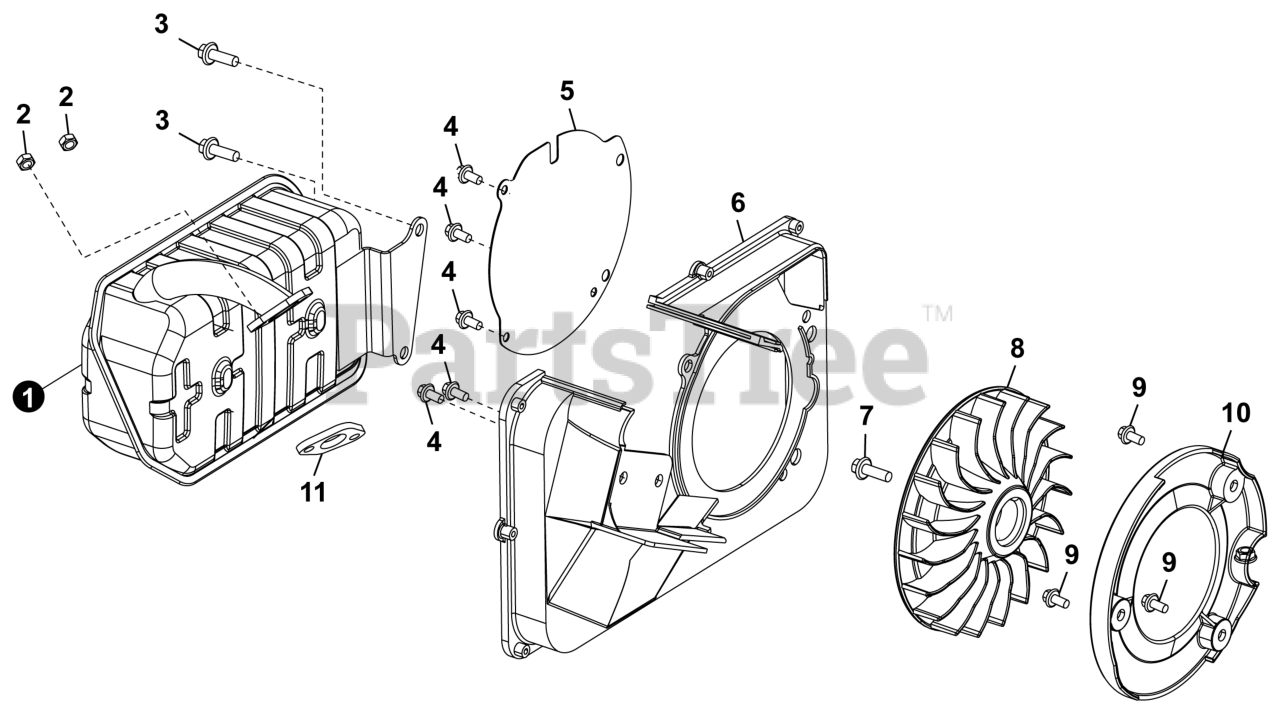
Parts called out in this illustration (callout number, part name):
1	ASSY., MUFFLER
5	PLATE, SEPARATOR
6	PLATE, MUFFLER INSULATOR
11	GASKET, EXHAUST OUTLET
